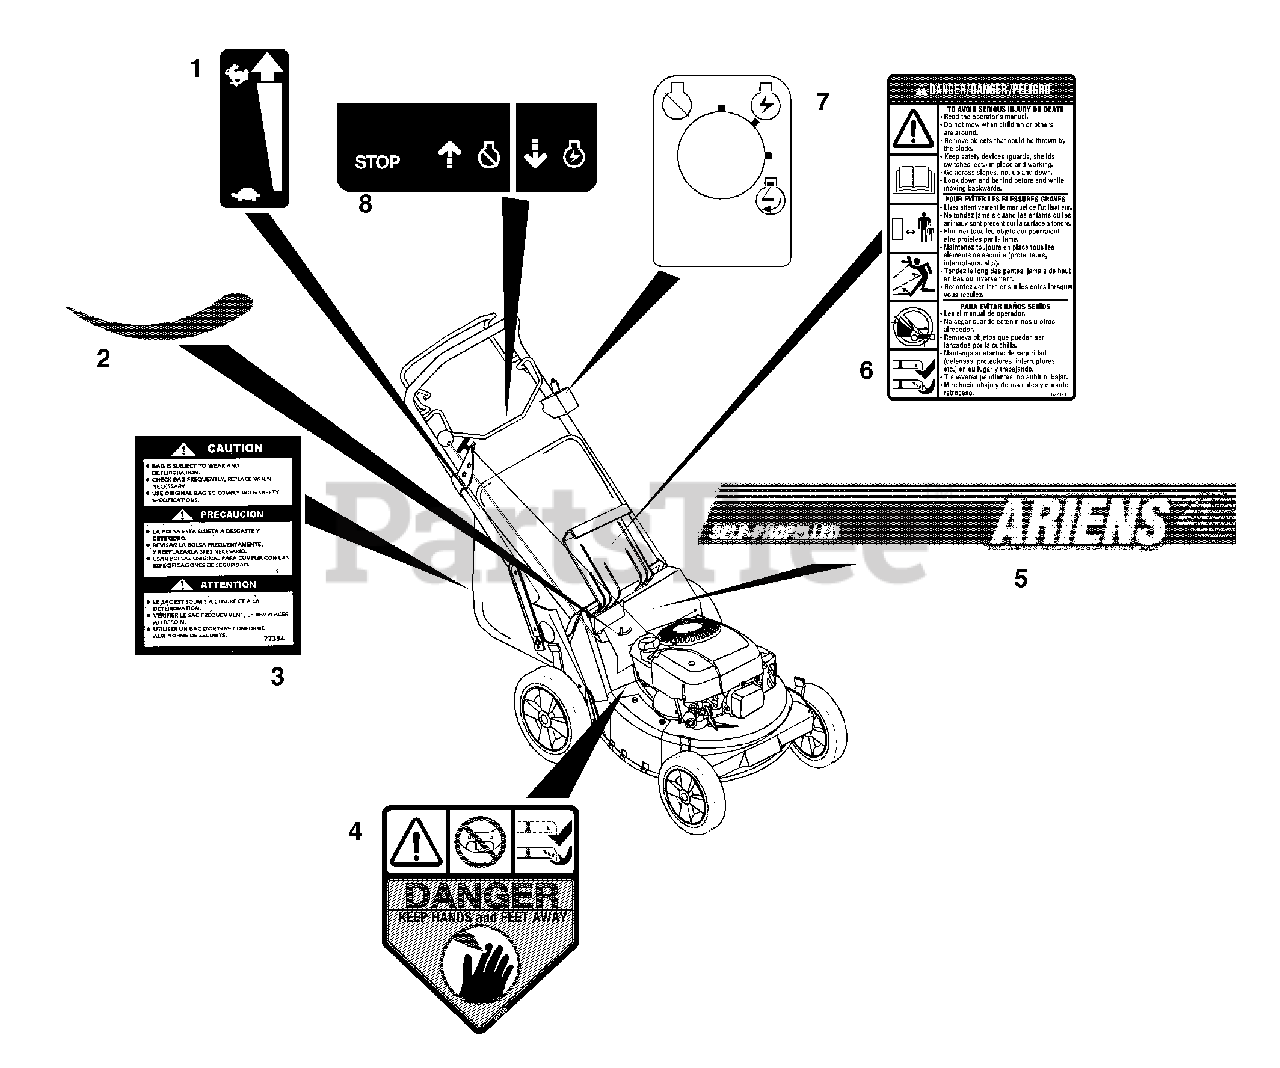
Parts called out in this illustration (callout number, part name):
1	DECAL-SPEED CONTROL
2	DECAL, SWOOSH
3	LABEL - BAGGER 21"
4	DECAL, DANGER
5	DECAL, ARIENS 21 SELF-PROP.
6	DECAL, BILINGUAL DANGER
7	DECAL-KEY SWITCH
8	DECAL - ENGINE CONTROL
